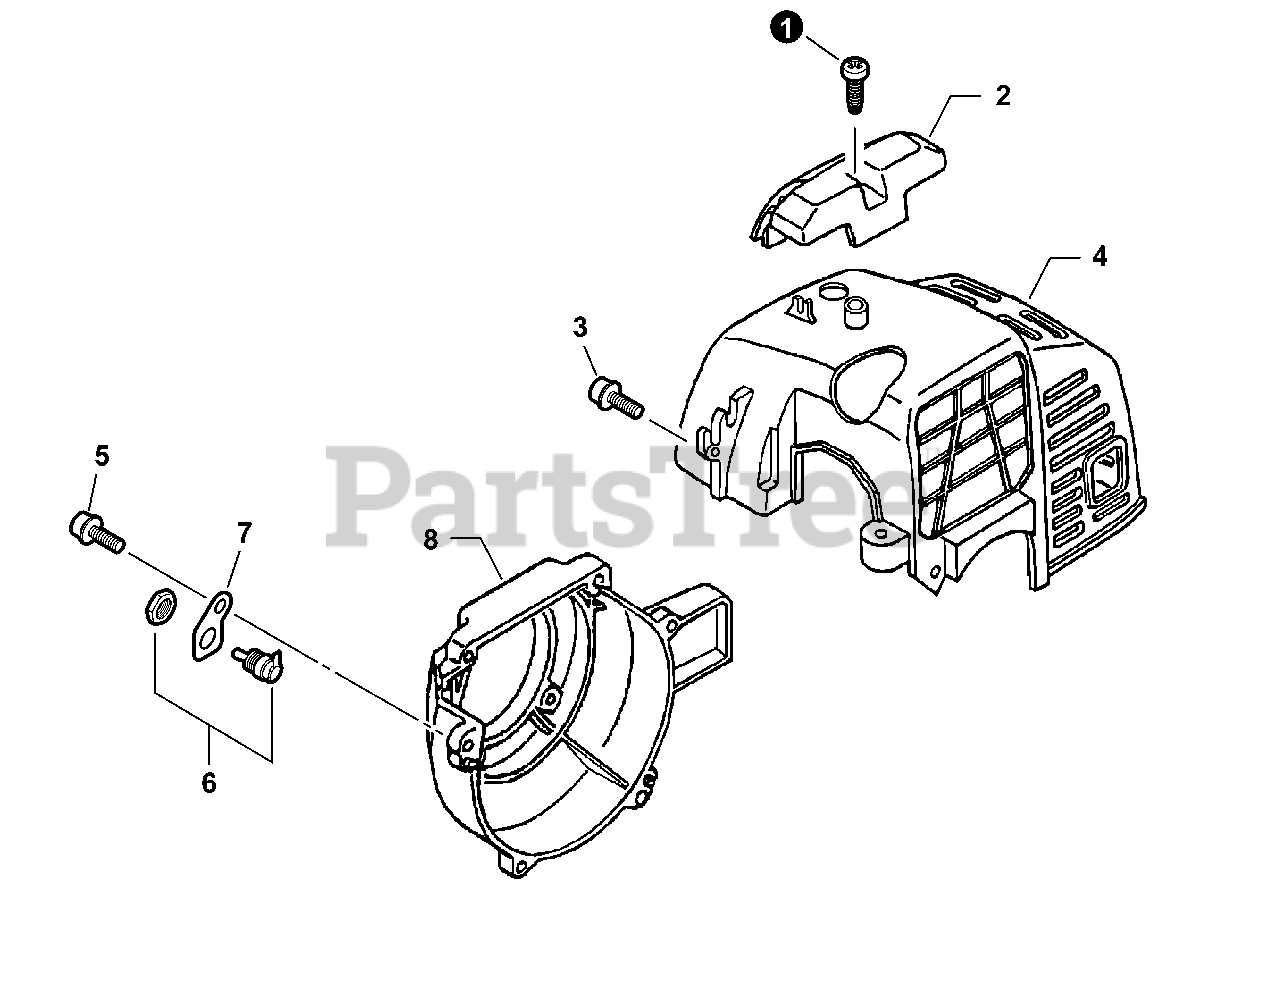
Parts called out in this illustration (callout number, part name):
1	SCREW 5×16
2	GUARD, TOP - GRAY
2	GUARD, TOP - BLACK
3	SCREW 4×12
4	COVER, ENGINE - GRAY
4	COVER, ENGINE - ORANGE
5	BOLT 4×16
6	SWITCH, ON-OFF
7	BRACKET, SWITCH
8	COVER, FAN - GRAY
8	COVER, FAN - ORANGE
